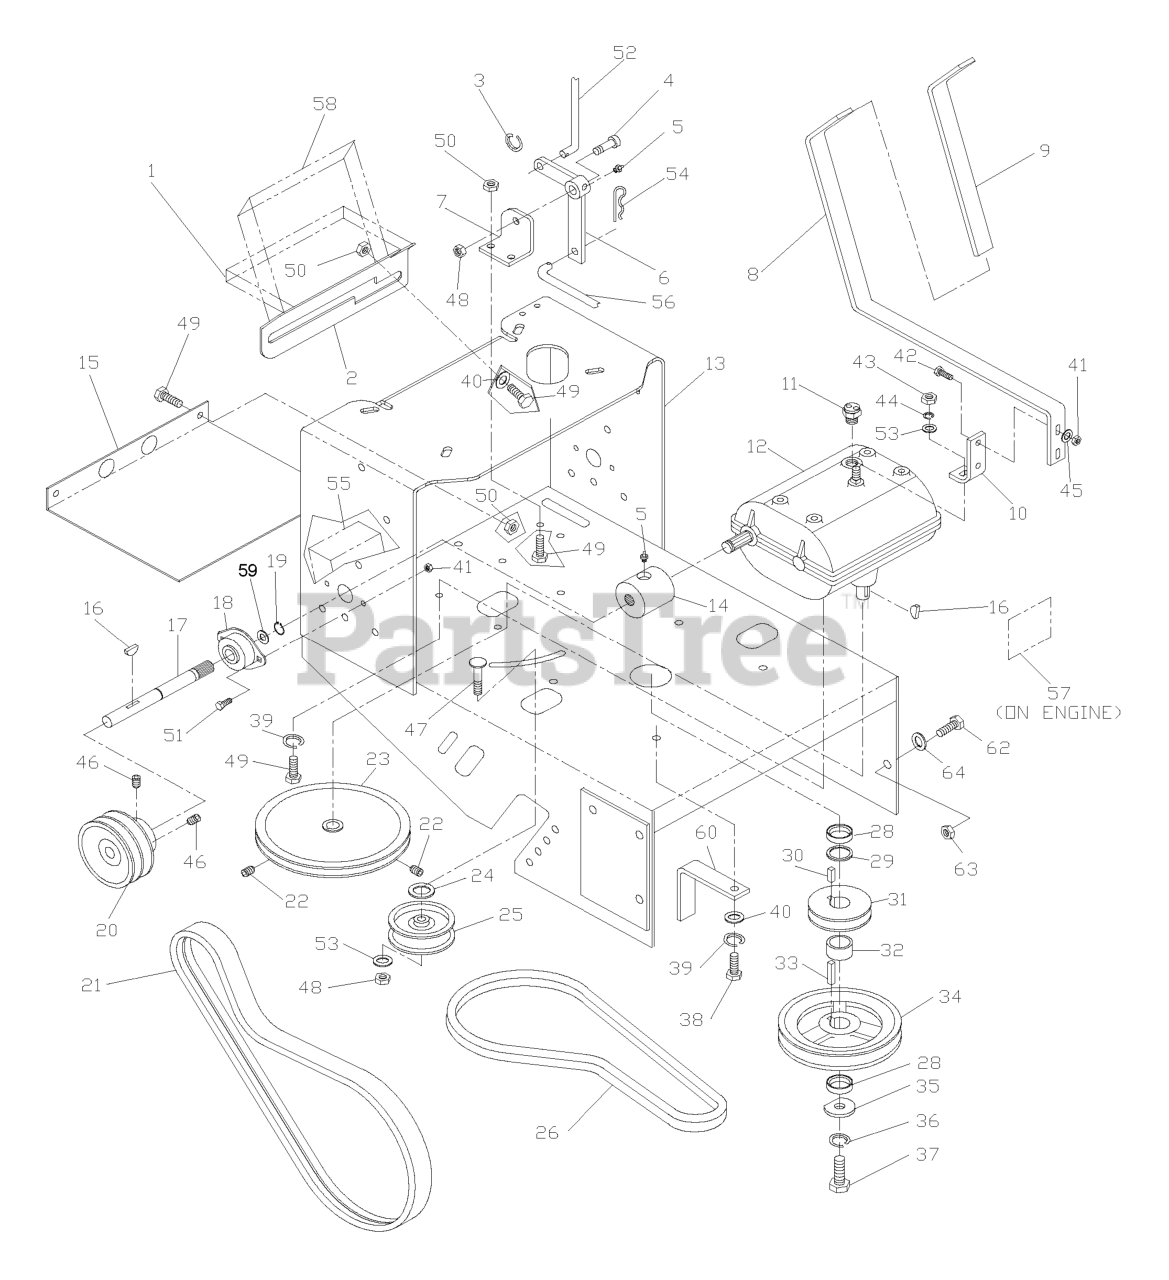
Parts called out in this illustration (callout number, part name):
1	DECAL, SHIFTER
2	SHIFTER PLATE
4	SB 12C X 34
5	ZERK
8	SHIFTER ARM
9	SHIFTER GRIP
10	SHIFTER BRACKET
11	SWITCH, TRANS
12	TRANSMISSION WB
13	REAR DECK W/DECALS
15	LOWER BELT SHIELD
16	KEY, #9 WOODRUFF
17	DRIVE SHAFT
19	RETAINER RING
20	PULLEY, DRIVE (36 & 48)
20	DRIVE PULLEY (32)
21	BELT, DRIVE 36/48
21	DRIVE BELT (32)
22	SETSCREW, 1/4-20 NYLOC
23	PULLEY, INPUT
24	WASHER 1/2 FLAT
25	IDLER PULLEY
26	BELT, TRANSMISSION
29	BUSHING, 10GA MACHINERY
30	SQUARE KEY - 1/4 X .5
33	KEY 1/4 SQ X 1 1/8
34	PULLEY, ENGINE
35	SPINDLE WASHER
36	WASHER 7/16 LOCK
37	HCS 7/16F X 1 1/2
38	HCS M8-1.25 X 30MM
39	WASHER.LOCK.HVY.HLCL.SPR.5/16
40	WASHER 5/16 FLAT
41	NUT 1/4C CENTER LOCK
42	HCS 1/4C X 1
44	SLW 3/8 STD
45	WASHER 1/4 FLAT
46	SET SCREW 5/16 NYLOC
47	RHSNB 3/8C X 2
48	NUT 3/8C CENTERBLOCK
49	HCS 5/16C X 3/4
50	NUT 5/16C CENTERLOCK
51	HCS 1/4C X 5/8
53	WASHER 3/8 FLAT
54	HAIRPIN #4
55	DECAL, BELT DRIVE
56	BLADE ROD 36"
57	DECAL, EXHAUST
58	DECAL, CLUTCH
59	BUSHING
60	BELT GUIDE - LONG
62	HCS 7/16C X 1 1/2
63	NUT 7/16C CENTERLOCK
64	WASHER 7/16 FLAT ZD
